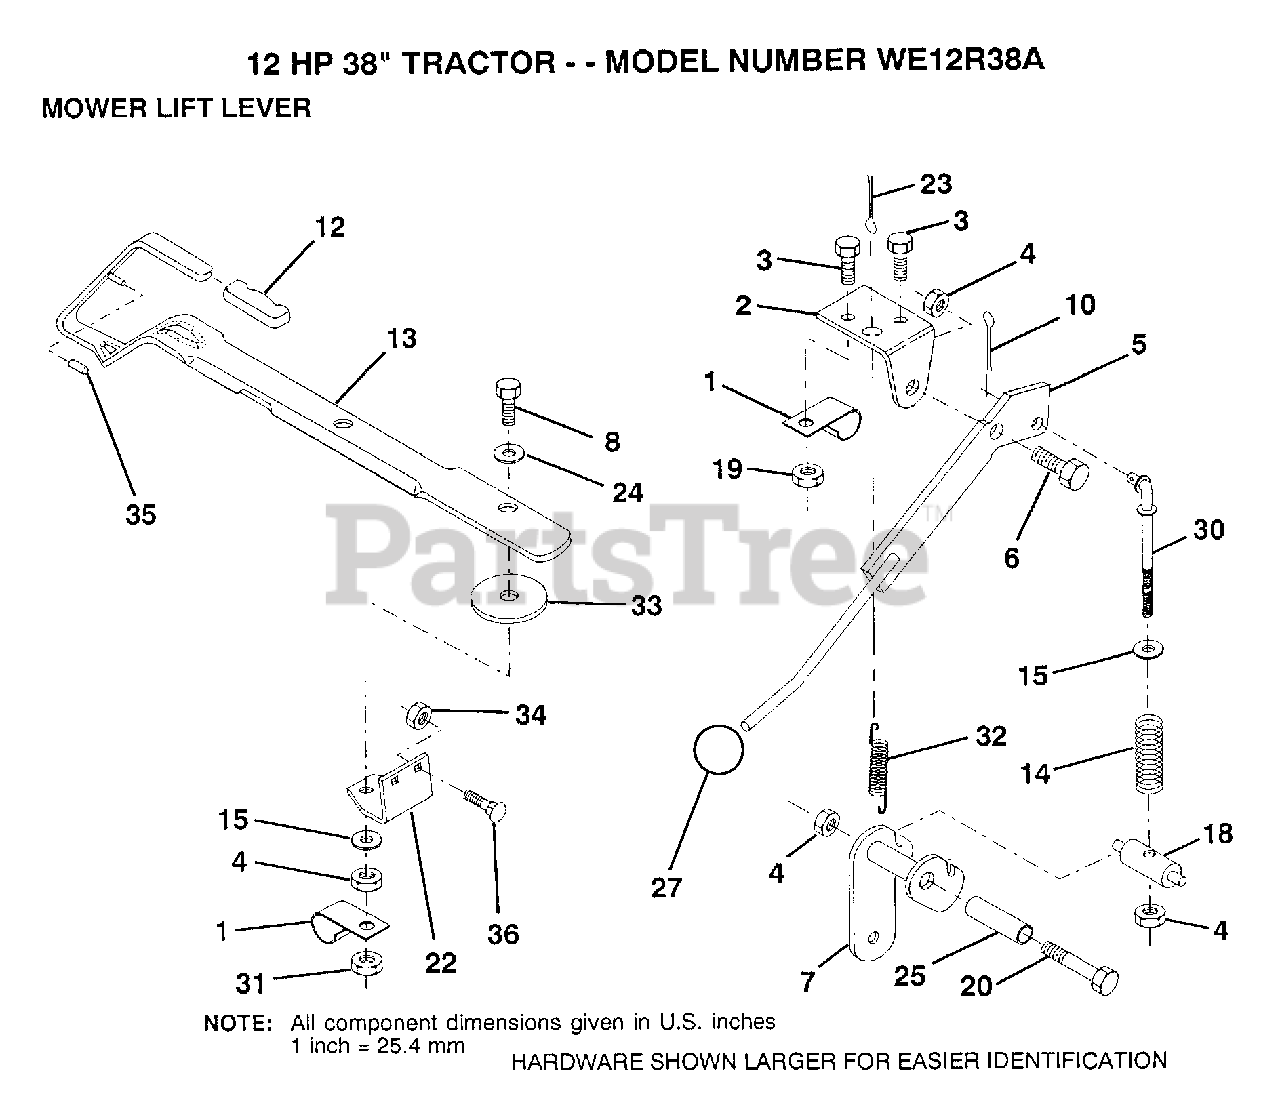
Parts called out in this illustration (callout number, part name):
1	"CLIP,INSULATOR"
2	BRKT CLUTCH
3	BOLT
5	CLUTCH LEVER AS
6	"BOLT, SHOULDER LT"
7	MWR CLUT ARM ASM
8	BOLT
10	COTTER PIN
12	GRIP HANDLE
13	LEVER LIFT LR
14	COMP CLUTCH SPRNG
15	WASHER HYT
18	TRUNNION
20	BOLT
22	LIFT LEVER BRKT
24	WASHER
25	TUBE SPACER
27	KNOB T(3/8 HOLE)
30	ROD TENSION CLUTC
31	LOCKNUT
32	SPRING EXT
33	WASHER
35	VINYL CAP RED
36	BOLT
